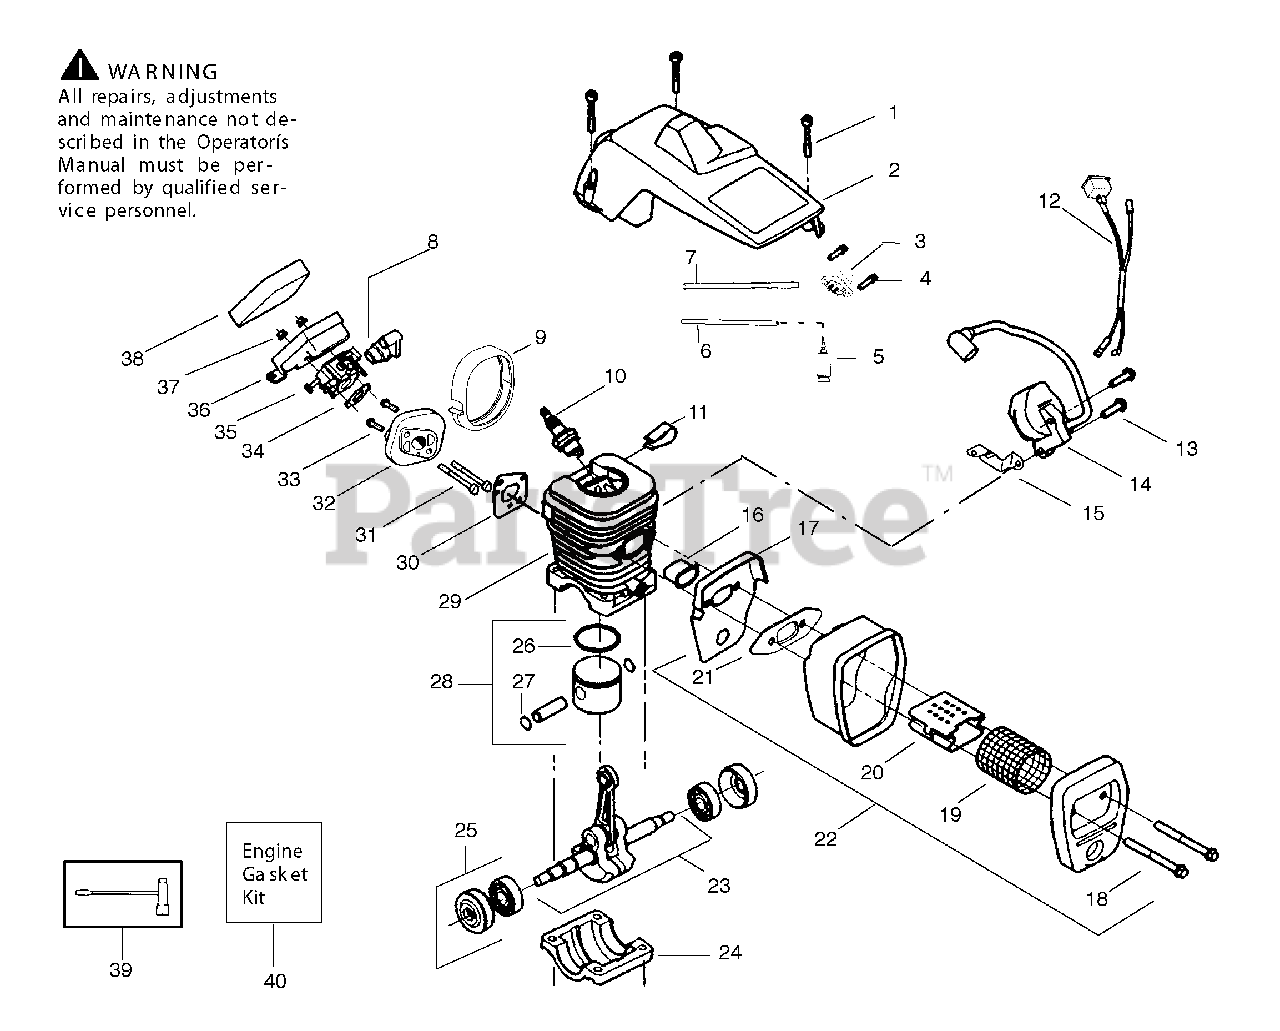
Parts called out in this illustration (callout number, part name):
5	FUEL PICK-UP ASSY
8	GROMMET-CARB ADJUST
10	SPARK PLUG (RCJ-7Y)
12	WIRE HARNESS ASS'Y
15	GROUND STRAP
16	HEAT INSULATOR
20	FLAME PROTECTION
22	MUFFLER
23	CRANKSHAFT
25	BEARING & SEAL ASSEMBLY
26	RING-PISTON
27	C-CLIP,PSTN PIN 36/41
29	KIT-CYLINDER
32	PARTITION
36	AIR FILTER HOUSING
38	AIR FILTER
39	SCRENCH
5300476-30	DECAL STOP
5300697-22	CARBURETOR
5300716-21	KIT-CARBURETOR (WT-625)
